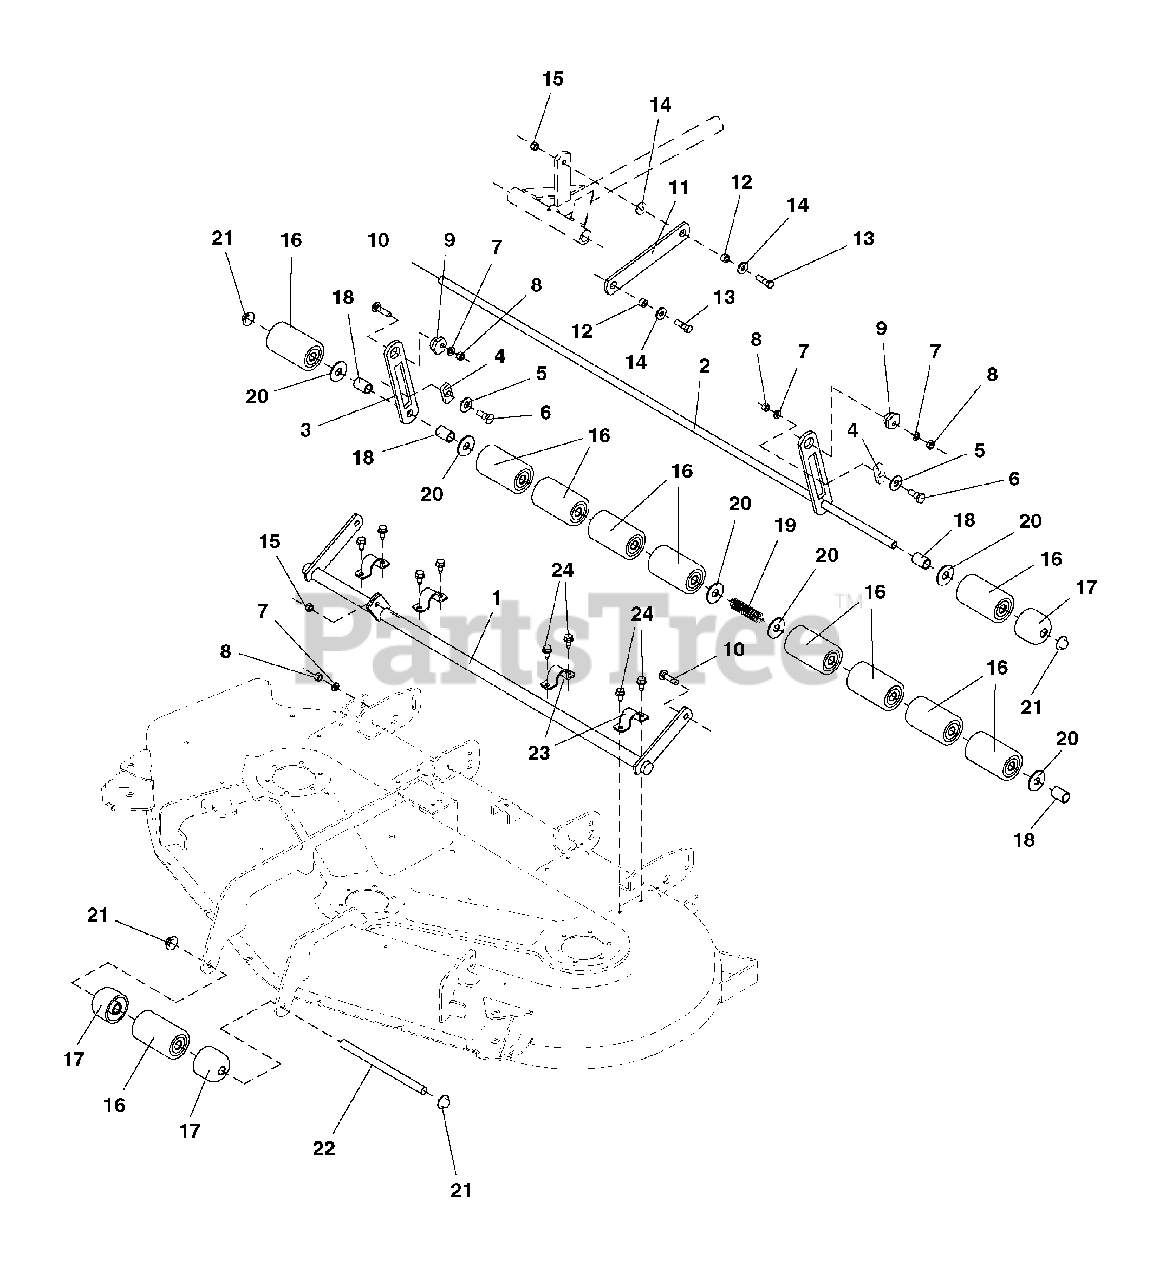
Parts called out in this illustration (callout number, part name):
1	ROCKER SHAFT ASSEMBLY
2	BAR & SHAFT ASSEMBLY, Roller
3	BAR, Roller
5	WASHER, 1/2
6	BOLT, Shoulder, 3/8-16 X 1.34
7	LOCKWASHER, 3/8
8	NUT, Hex, 3/8-16
9	NUT, Hex Adjusting, .99 DIA .687
10	CARRIAGE BOLT, 3/8-16 x 1-1/2
11	LINK, Roller Height
13	CAPSCREW, Hex Hd, 3/8-16 x 1-1/4
14	WASHER, 3/8
15	NUT, Hex, Center Lock, 3/8-16
16	ROLLER, Inner
17	ROLLER, Outer
19	SPRING, Compression
20	WASHER, 5/8
21	NUT, Push, 5/8
22	SHAFT, Roller
23	STRAP
24	SCREW, Hex Washer Hd, Taptite, 5/16-18 x 3/4
